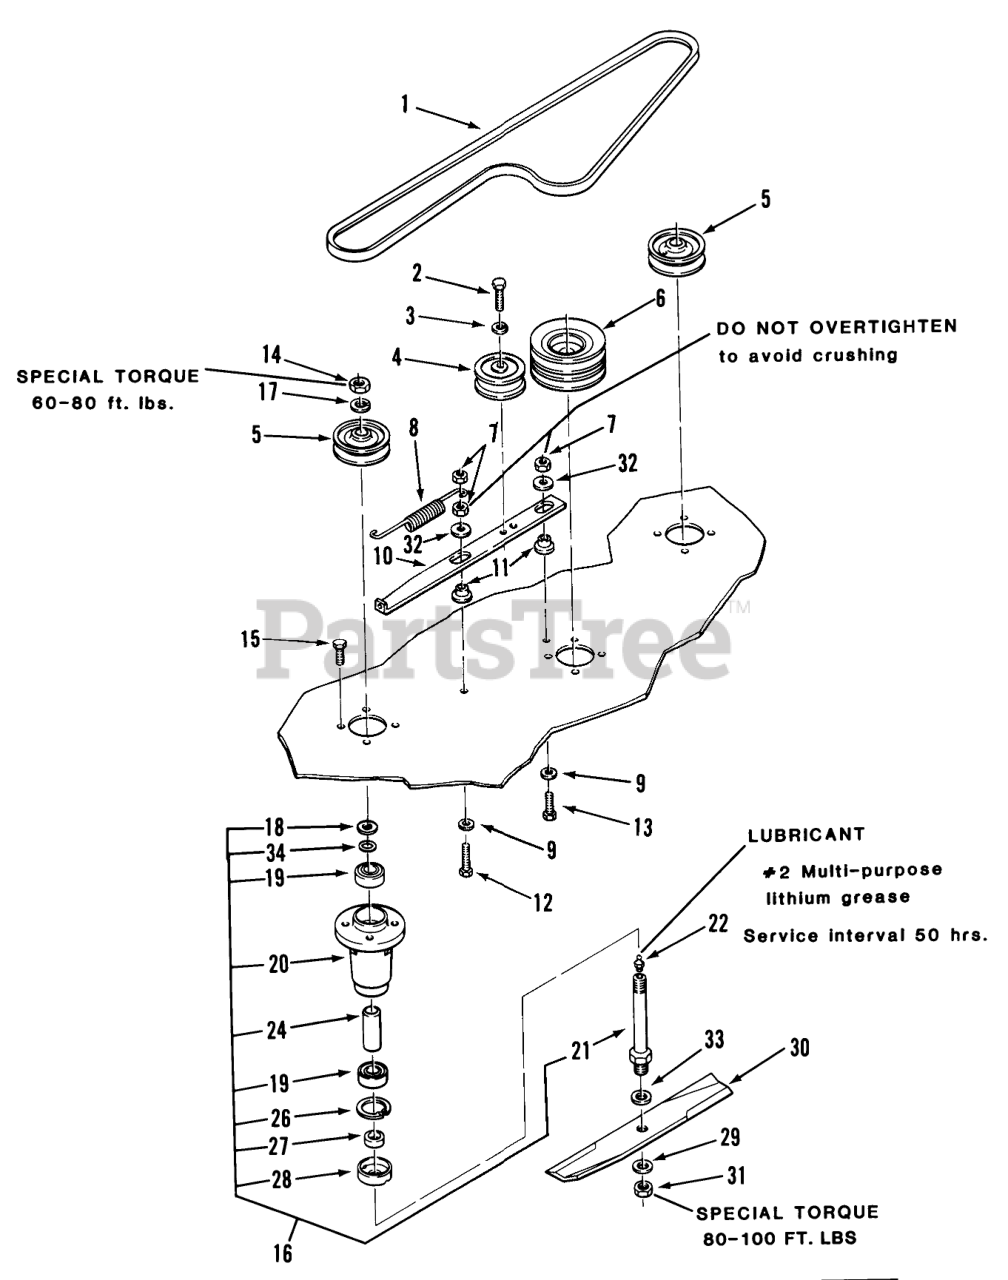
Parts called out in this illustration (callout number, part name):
1	V-BELT
2	BOLT HEX SPECIAL
3	LOCKWASHER
4	PULLEY-IDLER
5	PULLEY
6	PULLEY CENTER
7	NUT
8	SPRING-EXTENSION
9	WASHER
10	BAR-IDLER SUPPORT
11	SPACER-BUSHING
12	Bolt
13	Bolt
14	Jam Nut
15	Bolt
16	ASSY 36" SPINDLE
17	Lockwasher
18	Washer
19	BEARING-BALL
20	HOUSING-SPINDLE
21	SHAFT-SPINDLE
22	Zerk
24	Spacer
26	Ring-Snap
27	SPACER-BLADE
28	CUP-SPINDLE
29	SpeciaI Washer
30	S/A BLADE KIT
31	Nut-Jam
32	WASHER
33	Washer
34	O RING
